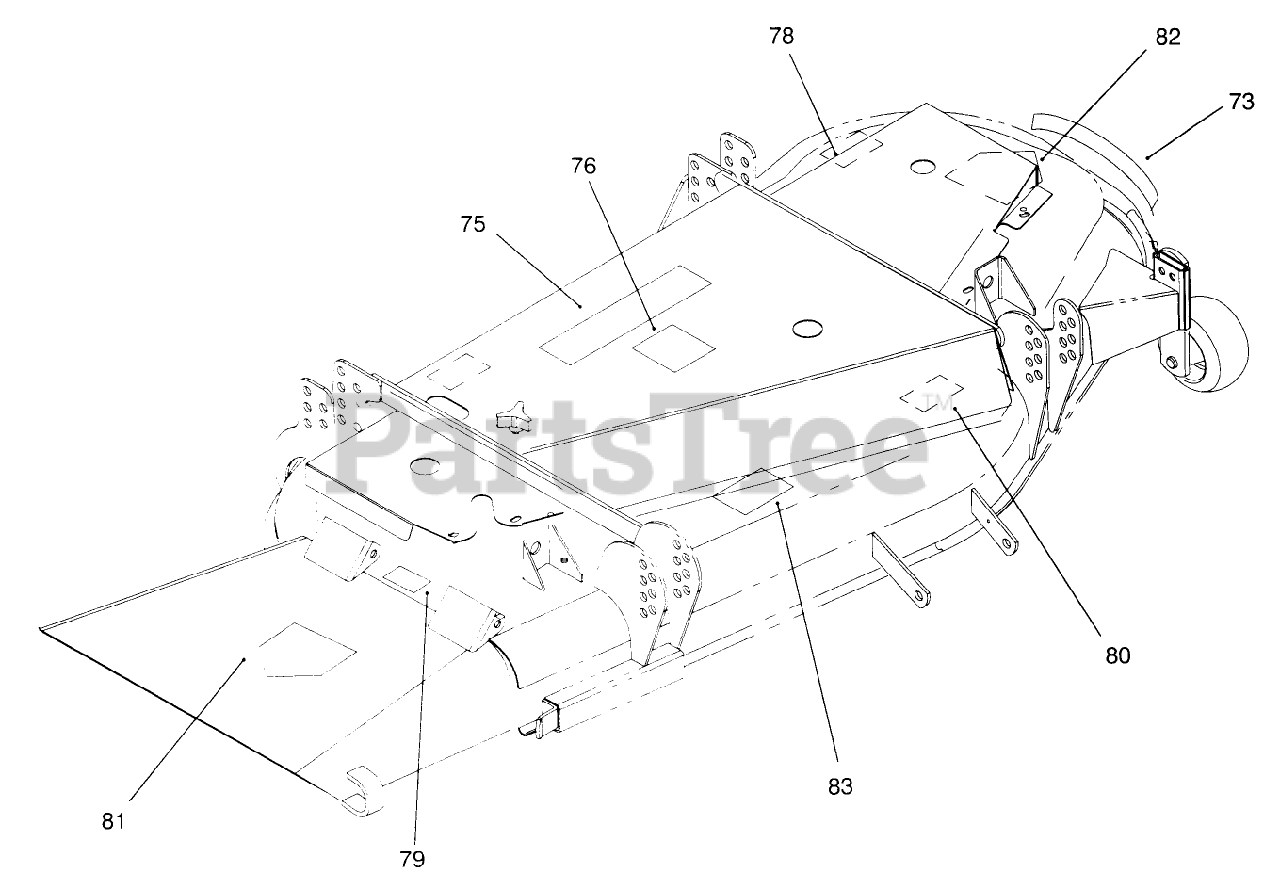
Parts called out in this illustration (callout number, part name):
73	DECAL-RECYCLER
75	DECAL-PROLINE
76	DECAL
78	DECAL-TORQUE
79	DECAL-DANGER
80	DECAL-DANGER
81	DECAL-DANGER
82	DECAL-DANGER
83	DECAL-DANGER, THROWN OBJECT
